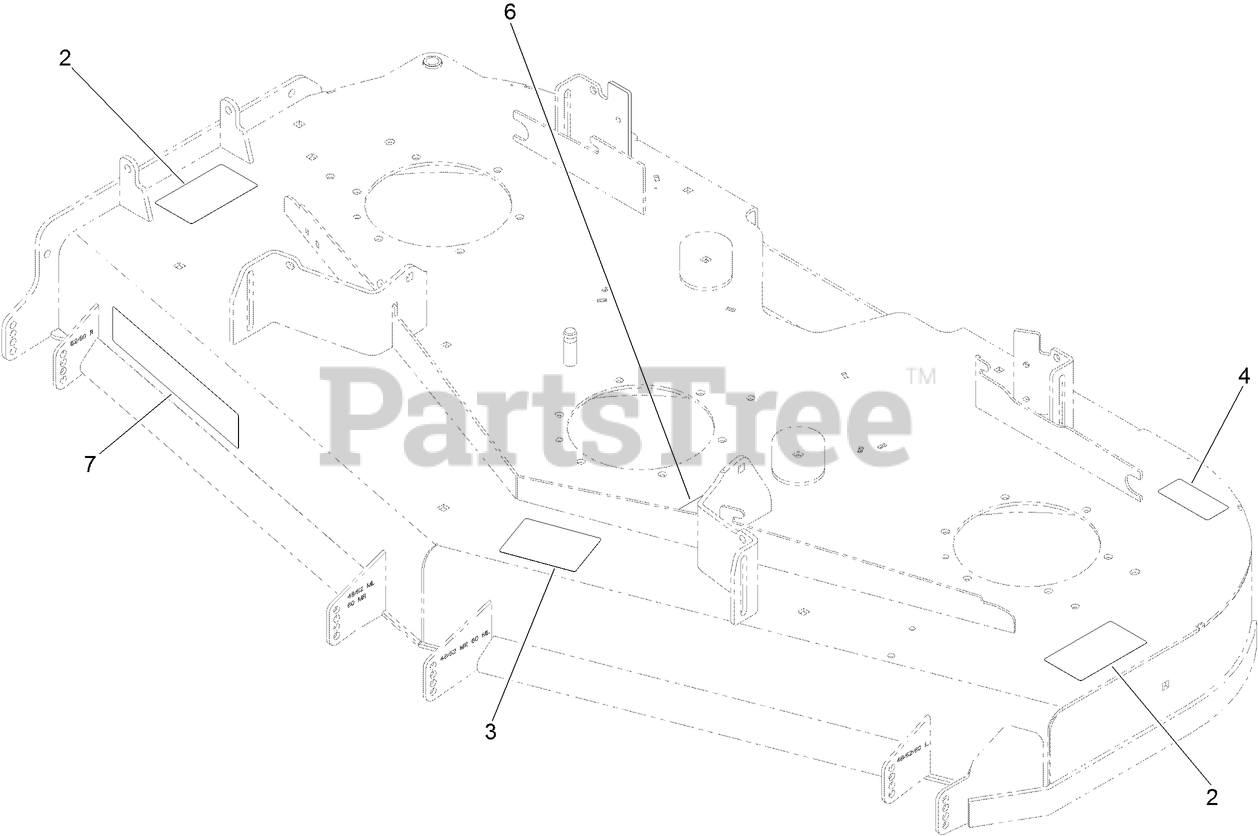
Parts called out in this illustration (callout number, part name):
2	DECAL-DANGER
3	DECAL-SCALP, ANTI
4	DECAL-BOLT TORQUE
6	DECAL-ROUTING, BELT
